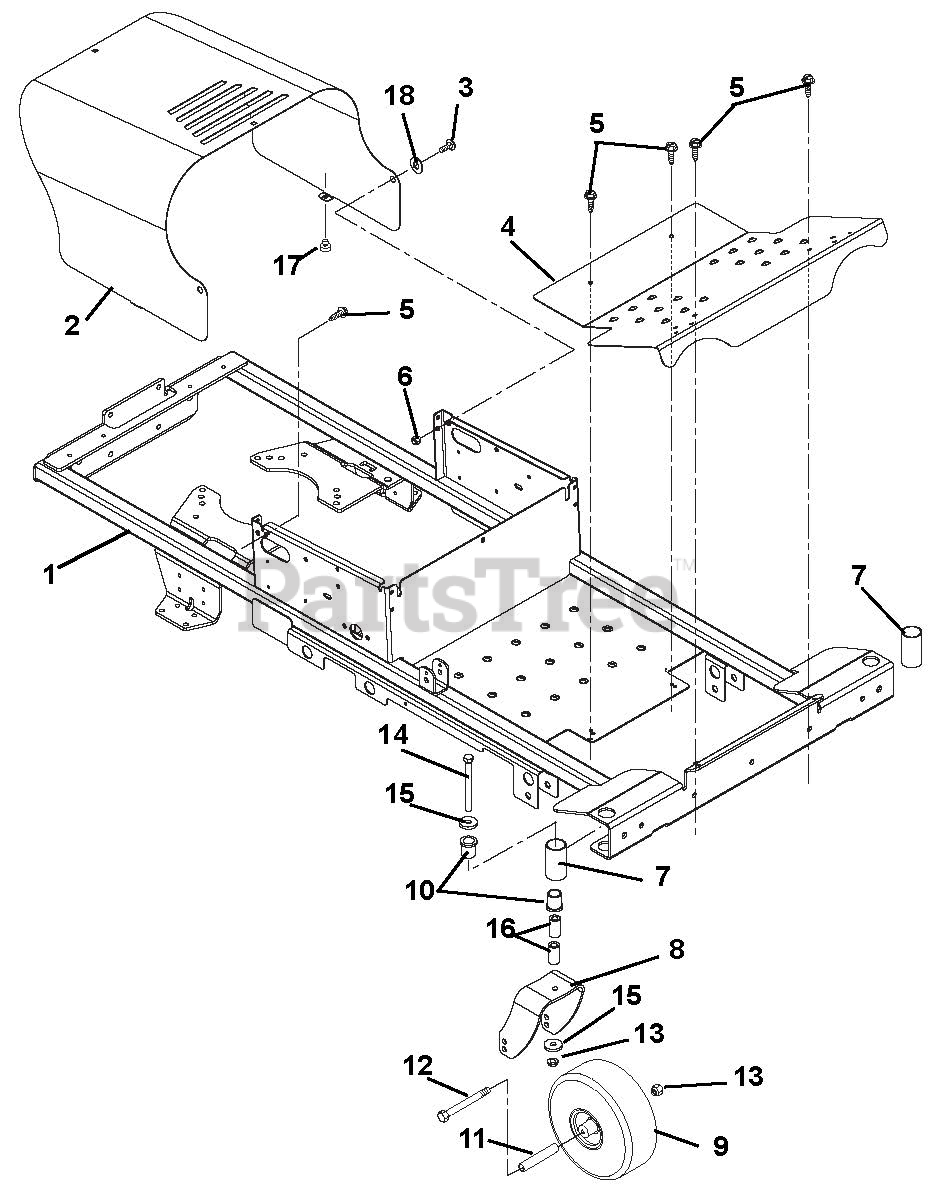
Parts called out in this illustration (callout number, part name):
1	WMT,MZ FRAME
2	ARIENS ENGINE COVER
3	BOLT-SHLDR .375-16X.150
4	ARIENS FOOTREST,MZ/MZT
5	@SCR-TAP .31-18X.50 HWH TR YWZ
6	@NUT-LK-TOP-FLG .38-16 YWZC
7	SLEEVE,CASTER
8	FORK,CASTER
9	ASSY-TIRE 4 X 11 - 4 PLY
10	BSHG-FLG 1.00X1.25X1.50X1.50EP
11	SPACER, ROLLED WHEEL
12	@BLT-HEX .50-13X6.50 GR5 YWZC
13	@NUT-LK-TOP-FLG .50-13 YWZC
14	@BLT-HEX .50-13X5.00 GR8 YWZC
15	WSHR-FL-STL .515X1.625X.250 YZ
16	SPACER, CASTER .50X1.00X1.84
17	BUTTON BUMPER
18	WSHR-FL-NYL .518X1.000X.080
